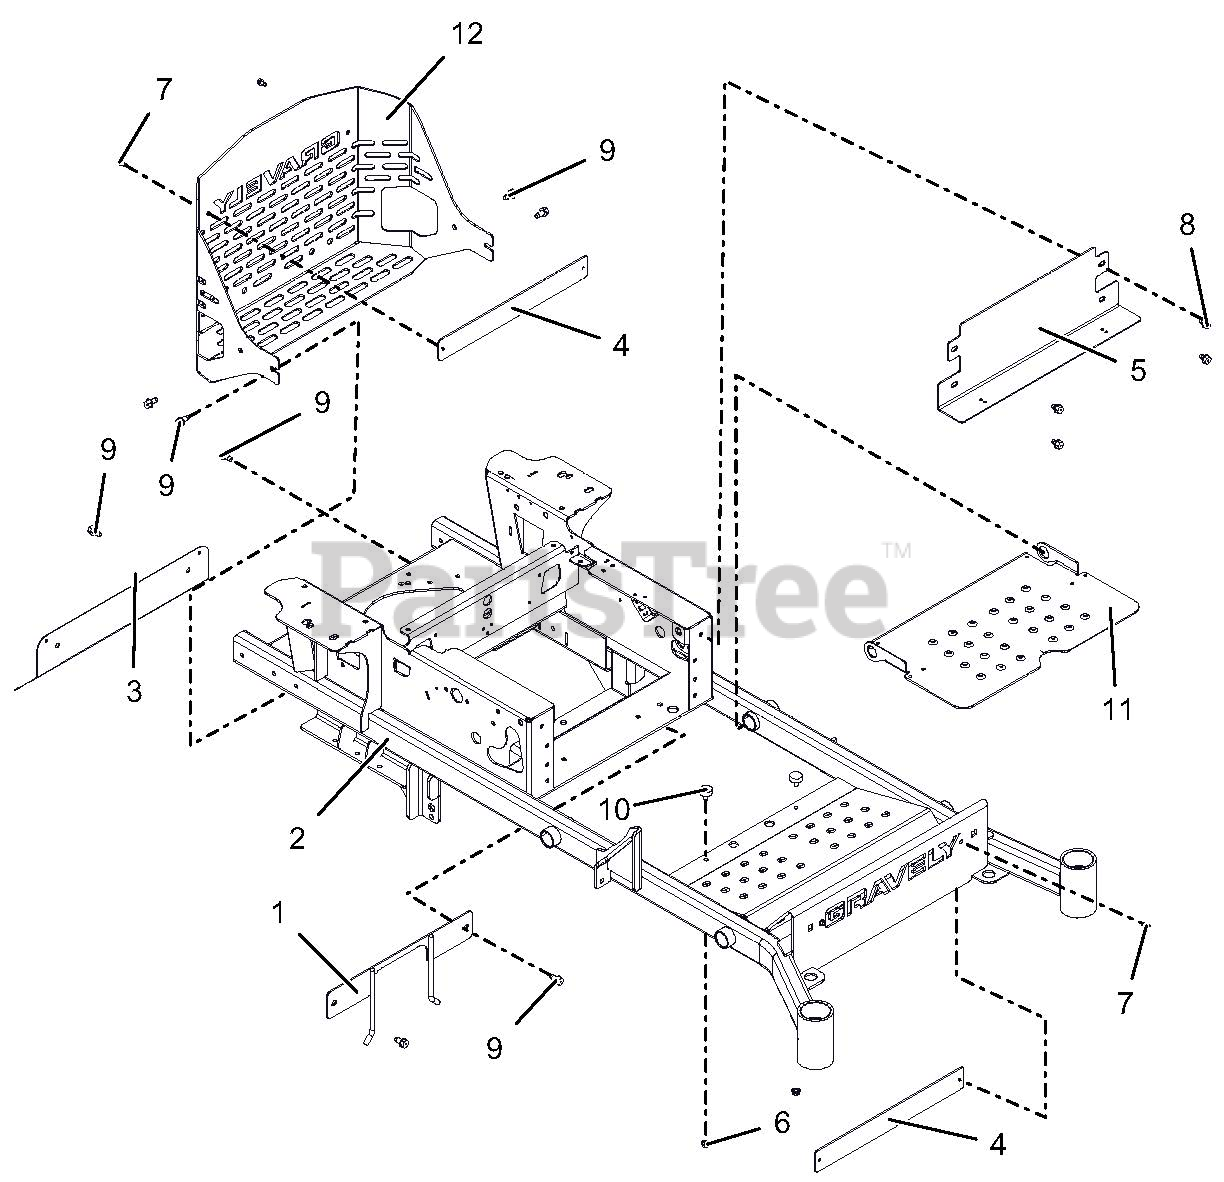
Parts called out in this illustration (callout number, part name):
1	WLDMT, PTO BELT FINGER-BLACK
2	WLDMT, PT/PT100 48-52" MAIN FRAME-RED
3	SHIELD, MUFFLER HEAT
4	PLATE, BUMPER 2.00 x 16.50 - BLK
5	PLATE, PT/PT100 KICK-RED
6	@NUT-SPNLK-FLG .312-18 YWZC
7	SCR-TAP .25-20X.50 HWH TR YWZ
8	SCR-TAP .38-16X.50 HWH TR YWZ
9	SCR-TAP .38-16X.75 HWH TR YWZ
10	BUMPER, RUBBER
11	FOOT, PLATE W/SAFETY DECALS
12	REAR BUMPER W/SAFETY DECALS
